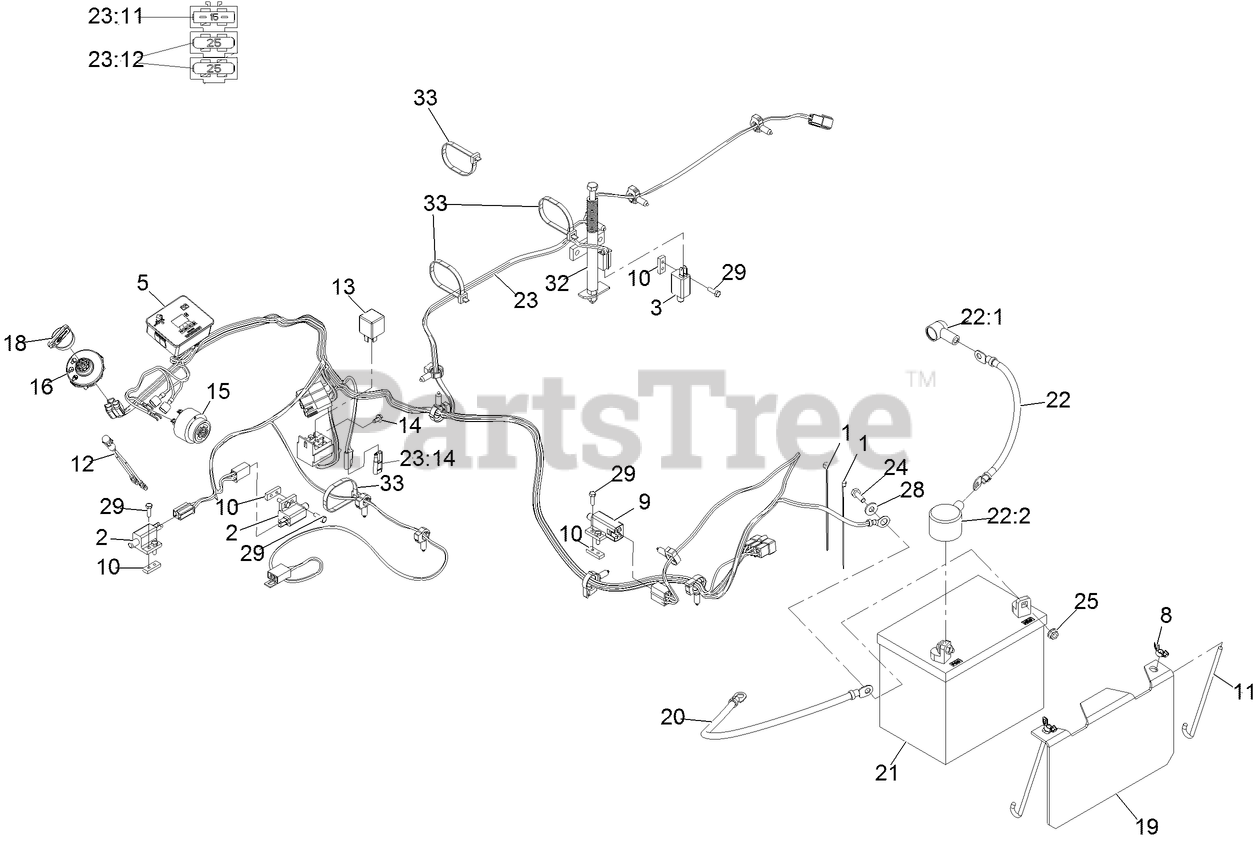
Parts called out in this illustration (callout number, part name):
1	TIE-CABLE
2	SWITCH-OPEN, NORMALLY
3	SWITCH-CLOSED, NORMALLY
5	HOUR METER ASM
8	WINGNUT
10	PLATE-TAPPED
11	BOLT-HOLDDOWN
12	INDICATOR-LED, RED
14	SCREW-HWH
15	ALARM-TONE, DUAL
16	SWITCH-IGNITION
18	KEY-IGNITION
19	HOLD DOWN-BATTERY
20	CABLE-BATTERY, NEGATIVE
21	BATTERY
22	CABLE-BATTERY, POSITIVE
22:1	INSULATOR-SOLENOID
22:2	INSULATOR-BATTERY
23	HARNESS-WIRING
23:11	FUSE-BLADE, 15 AMP
23:12	FUSE-BLADE, 25 AMP
23:14	CAP-PLUG
24	SCREW-HH
28	WASHER-FLAT
32	HOPPER SWITCH ACTUATOR AS
33	TIE-CABLE
